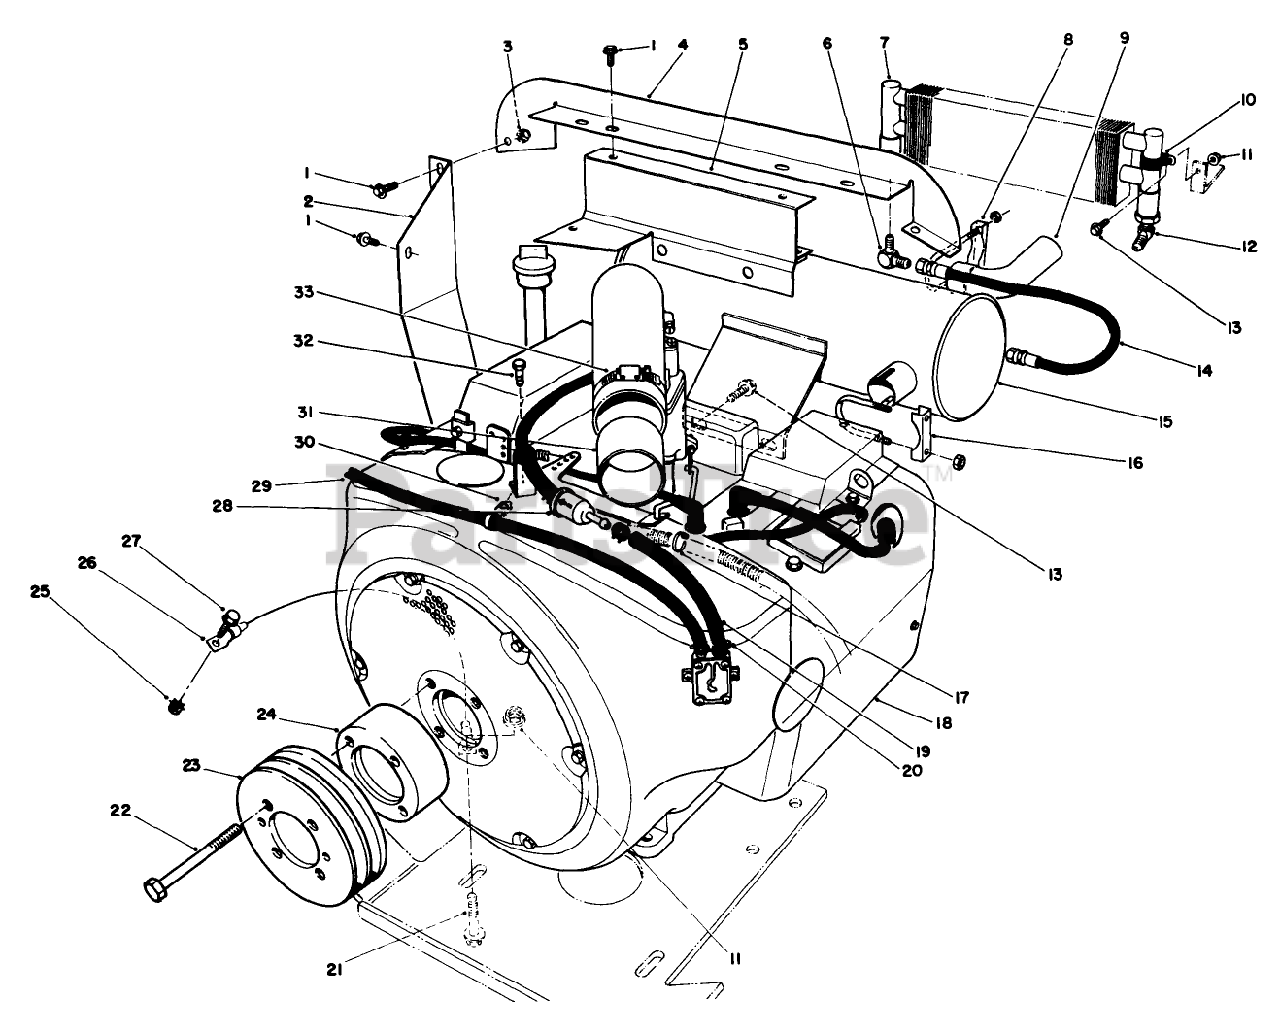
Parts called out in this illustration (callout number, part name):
1	SCREW-HHF
2	Shield-Heat
3	NUT-LOCK, NI
4	Shroud-Engine
5	Bracket-Shield Support
6	90DEG JIC FITTING
7	OIL COOLER
8	CLAMP
9	EXTENSION
10	CLAMP-R
11	NUT-HHF, WHIZ
12	ELBOW
13	SCREW-HHF
14	OIL HOSE ASM
15	MUFFLER
16	MUFFLER CLAMP
17	TIE-CABLE
18	Engine (Onan Model No. P220G-I/10808C
19	Hose
20	CLAMP-HOSE
21	SCREW-HHF
22	SCREW
23	Pulley-Engine
24	PULLEY SPACER
25	NUT-KEPS
26	WIRE ASM
27	SCREW-HHF
28	FILTER-FUEL
29	HOSE
30	CLAMP-R
31	AIR CLEANER ADAPTER
32	SCREW-HWHTF
33	CLAMP-HOSE
